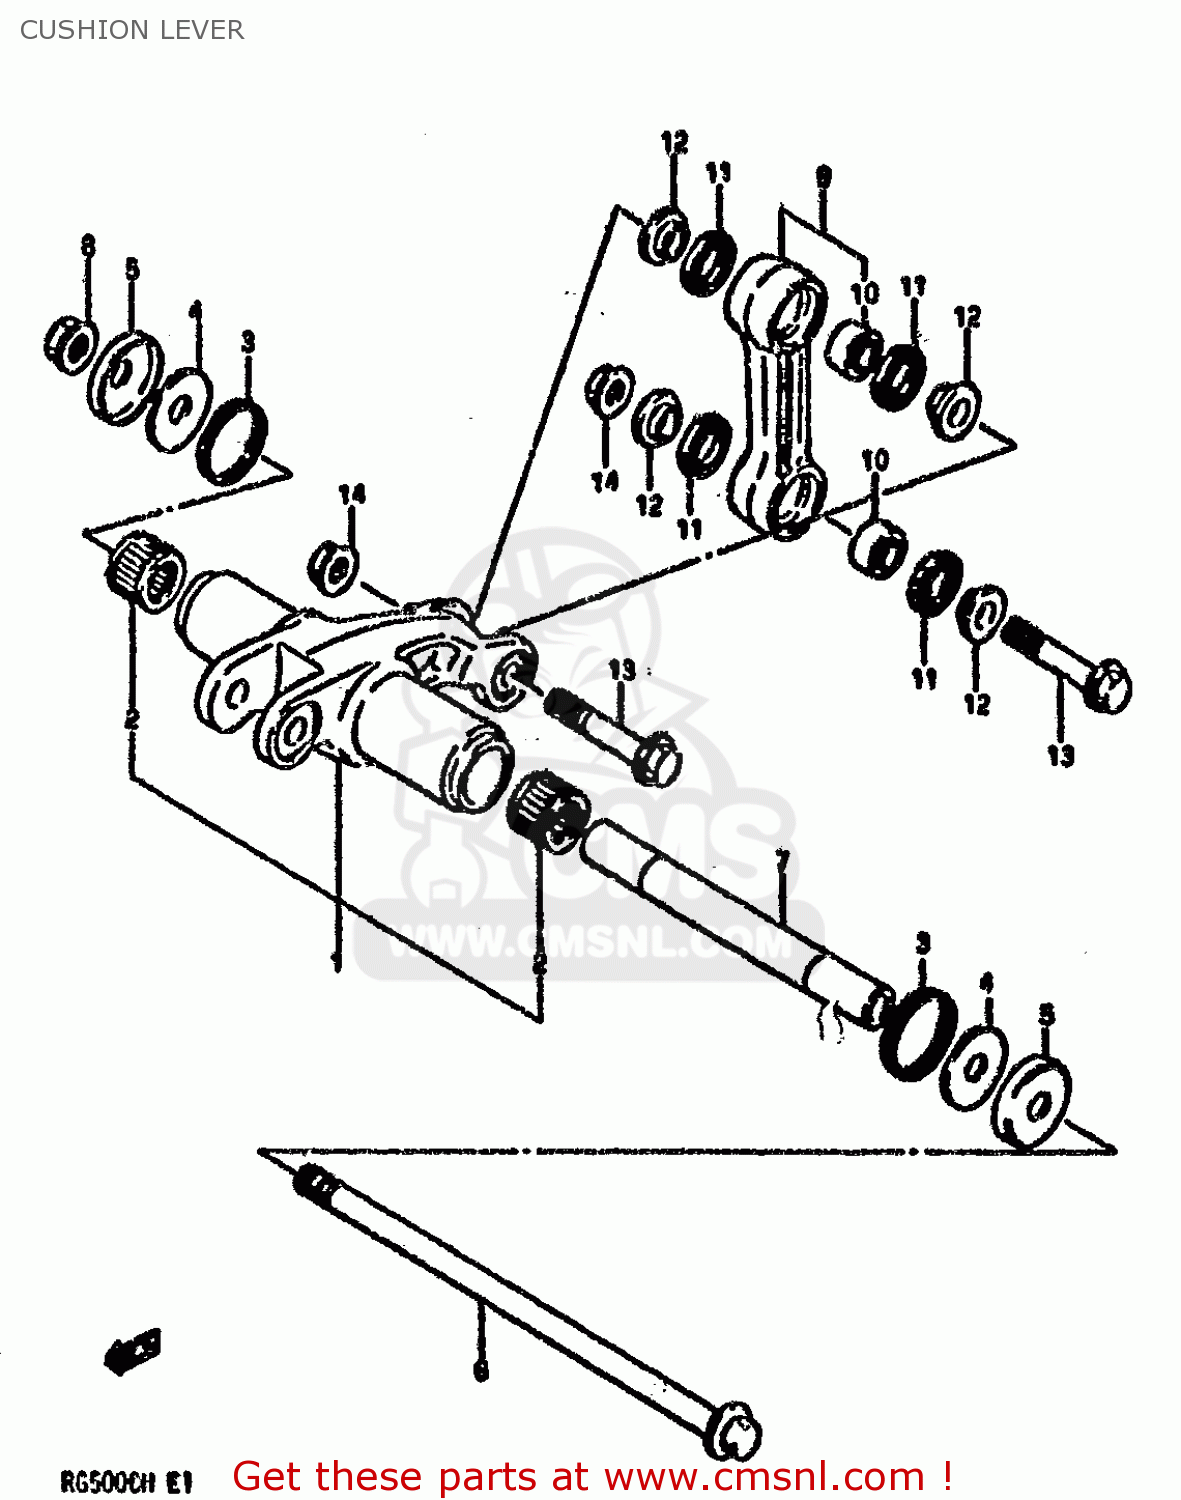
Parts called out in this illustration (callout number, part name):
1	LEVER SET,REAR CUSHION
2	BEARING(17X24X20)
3	DUST SEAL,RR CUSHION LEVER
4	WASHER
5	DUST COVER,REAR CUSHION
6	SHAFT,CENTER
7	SPACER,RR CUSHION LEVER CTR
8	NUT 12MM
9	ROD SET,REAR CUSHION LEVER
10	BEARING(10X21X13)
11	DUST SEAL,RR CUSHION LEVER RR
12	SPACER
13	BOLT(10X54)
14	NUT
